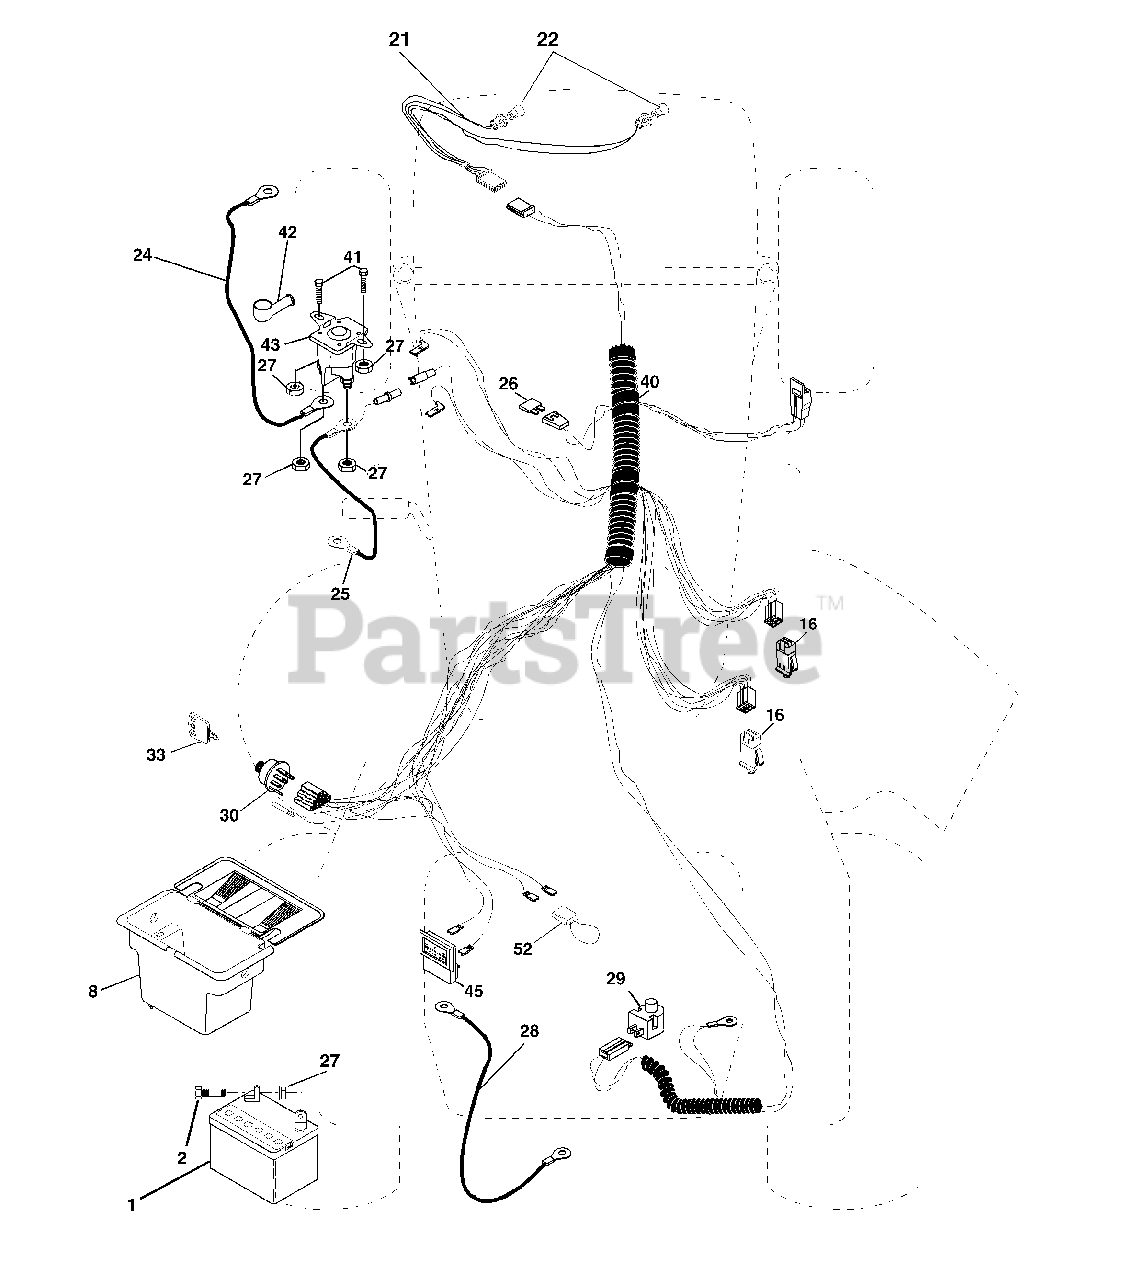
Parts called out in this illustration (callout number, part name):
1	Battery 12 Volt 25 Amp
2	Bolt Hex Hd 1/4-20unc X 3/4
8	Case Battery
16	Switch Interlock Push -In
21	Harness Asm Light W/4152J
22	Bulb Light #1156
24	Cable Battery 6 Ga 11"red
25	Cable Battery 6 Ga w/16 wire,red
26	Fuse 20 AMP
27	Nut Keps Hex 1/4-20 unc
28	Cable Ground 6 Ga 12" black
29	Switch Plunger Nc Gray
30	Switch Ign
33	Key Ign
40	Harness Ign
41	Bolt Blk Fin Hex 1/4-20 X 1/2
42	Cover Terminal Red
45	Ammeter
52	Protection Wire Loop
